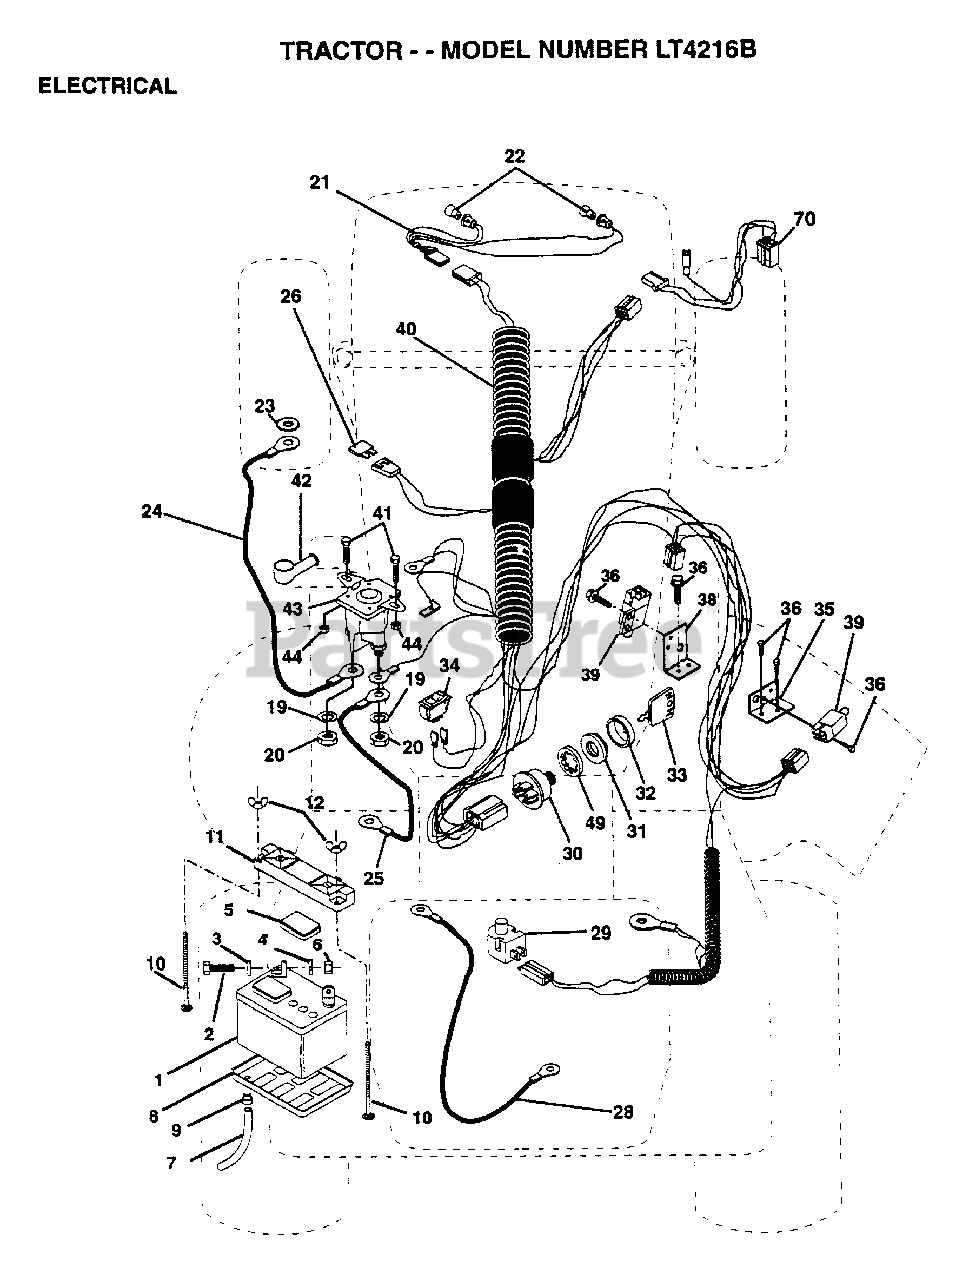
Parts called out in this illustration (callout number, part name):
2	BOLT LT
3	WASHER
4	LOCKWASHER
5	"CAP,BATTERY "
7	"DRAIN TU T, BATT"
8	"TRAY T, BATTERY"
9	HOSE CLAMP T
10	BOLT
20	NUT
21	"HARNESS,LIGHT SOC"
22	HEADLAMP BULB
23	LOCKWASHER
24	CABLE ASM.
25	CABLE-BATTERY T
26	FUSE HYT
28	CABLE T
29	SWITCH SEAT
32	COVER KEY SWITCH
33	KEY MLD GEN DELTA
34	SWITCH LT
35	BRACKET LT
36	SCREW
37	SWITCH-INTER. GT
38	BRACKET SWITCH IN
39	SWITCH INTERLOCKT
40	HARNESS IGN DASH
41	BOLT HXHD FIN
44	NUT HXKEP 1/4X20
49	LOCKWASHER
70	HARNESS ENG DUAL
